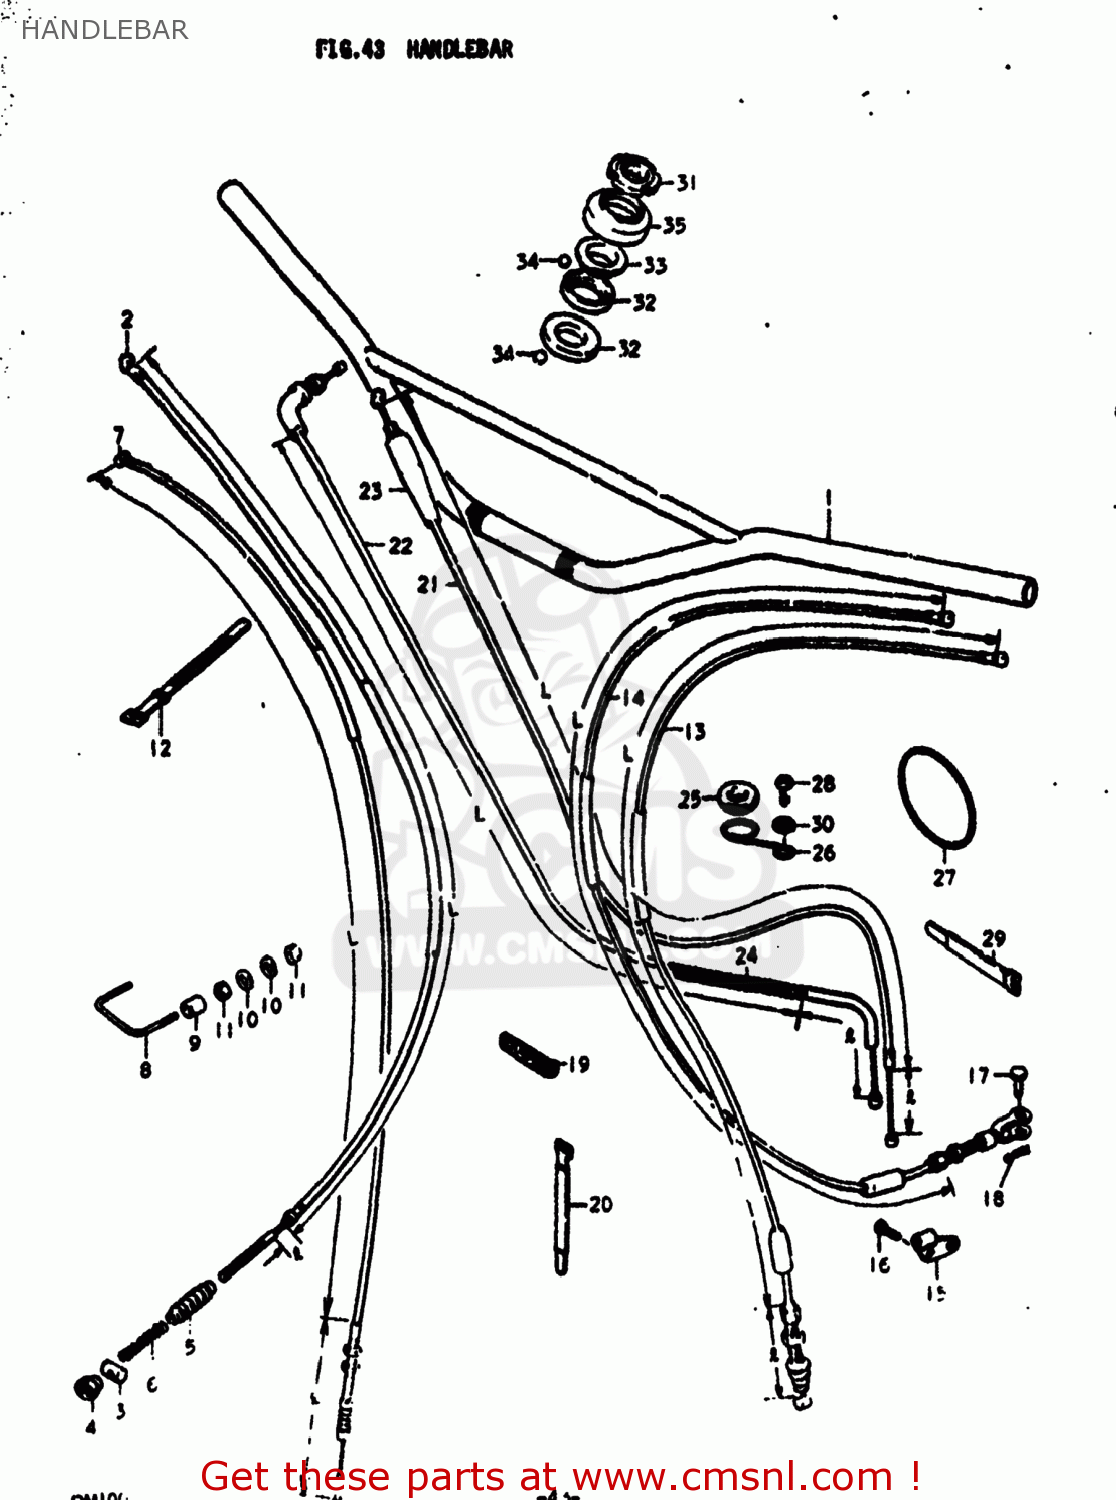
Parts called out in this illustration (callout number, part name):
1	HANDLEBAR
2	CABLE ASSEMBLY,FRONT BRAKE
3	PIN,10X19
4	NUT
5	SEAL,DUST(7X16X75)
6	SPRING
7	CABLE,FRONT BRAKE
8	CLAMP,CABLE
9	BUSHING
10	WASHER
11	NUT 3MM
12	CLAMP
13	CABLE ASSY,CLUTCH
14	CABLE ASSY,CLUTCH
15	STOPPER,CLUTCH CABLE
16	SCREW
17	PIN(L:13)
18	PIN
19	CLAMP L:35
20	CLAMP
21	CABLE ASSEMBLY,THROTTLE
22	CABLE ASSEMBLY,THROTTLE
23	SEAL
24	PROTECTOR,CABLE
25	GROMMET
26	CLIP
27	O RING(D:2.5,ID:68.5)
28	SCREW 6X12
29	CLAMP
30	LOCK WASHER
31	NUT,STEERING STEM(25X44X10)
32	LACE,STEERING INNER LWR
33	LACE,STEERING OUTER UPR
34	BALL
35	DUST SEAL,STEERING UPR
